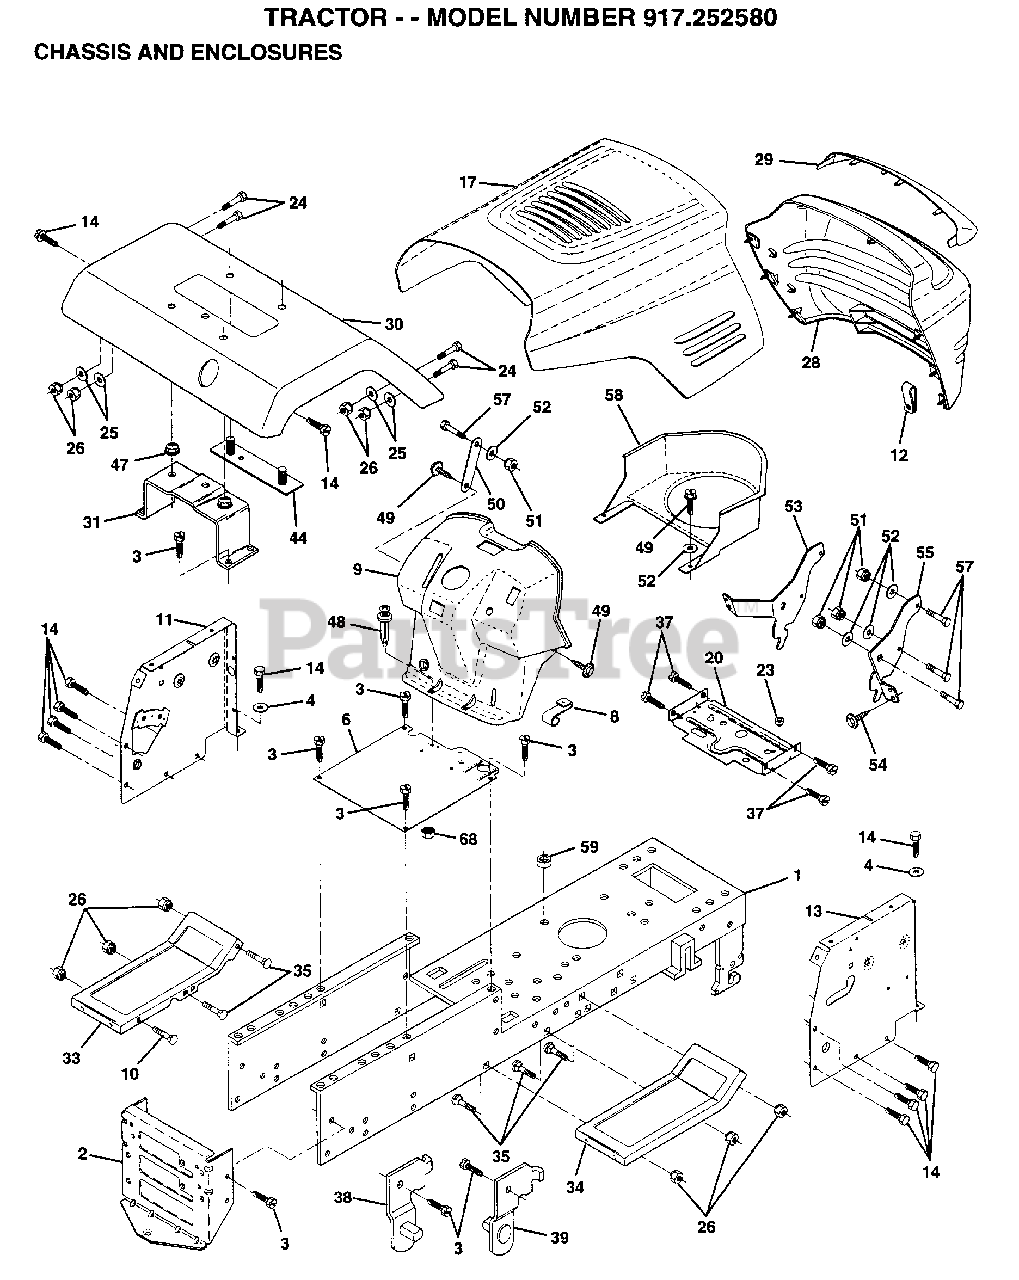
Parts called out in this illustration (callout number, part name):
1	CHASSIS.WLD.11GA
3	SCREW
4	WASHER
8	"CLIP,INSULATOR"
11	DASH PANEL LH
12	CLIP.TINNERMAN
14	SCREW LT
17	HOOD.W/SIDE-LOUVS
20	PLATE.MTG.BTRY.TK
24	BOLT
25	WASHER
26	NUT
31	BRKT.ASM.FENDER
33	FOOTREST.LH.LT-GT
34	FOOTREST.RH.LT-GT
35	BOLT
37	SCREW TI
38	BRACKET ASM LH
39	BRACKET ASM RH
44	STRAP ASM FENDER
47	NUT-PUSH YT
48	RIVET.PUSH.PLATE
49	SCREW HEX CRT
50	BRACE SUPT DASH
51	NUT
52	WASHER
53	BRACKET.GRILLE.LH
55	BRACKET.GRILLE.RH
58	DUCT AIR 12-15H
68	NUT
100	FOAM-STRIP LT
